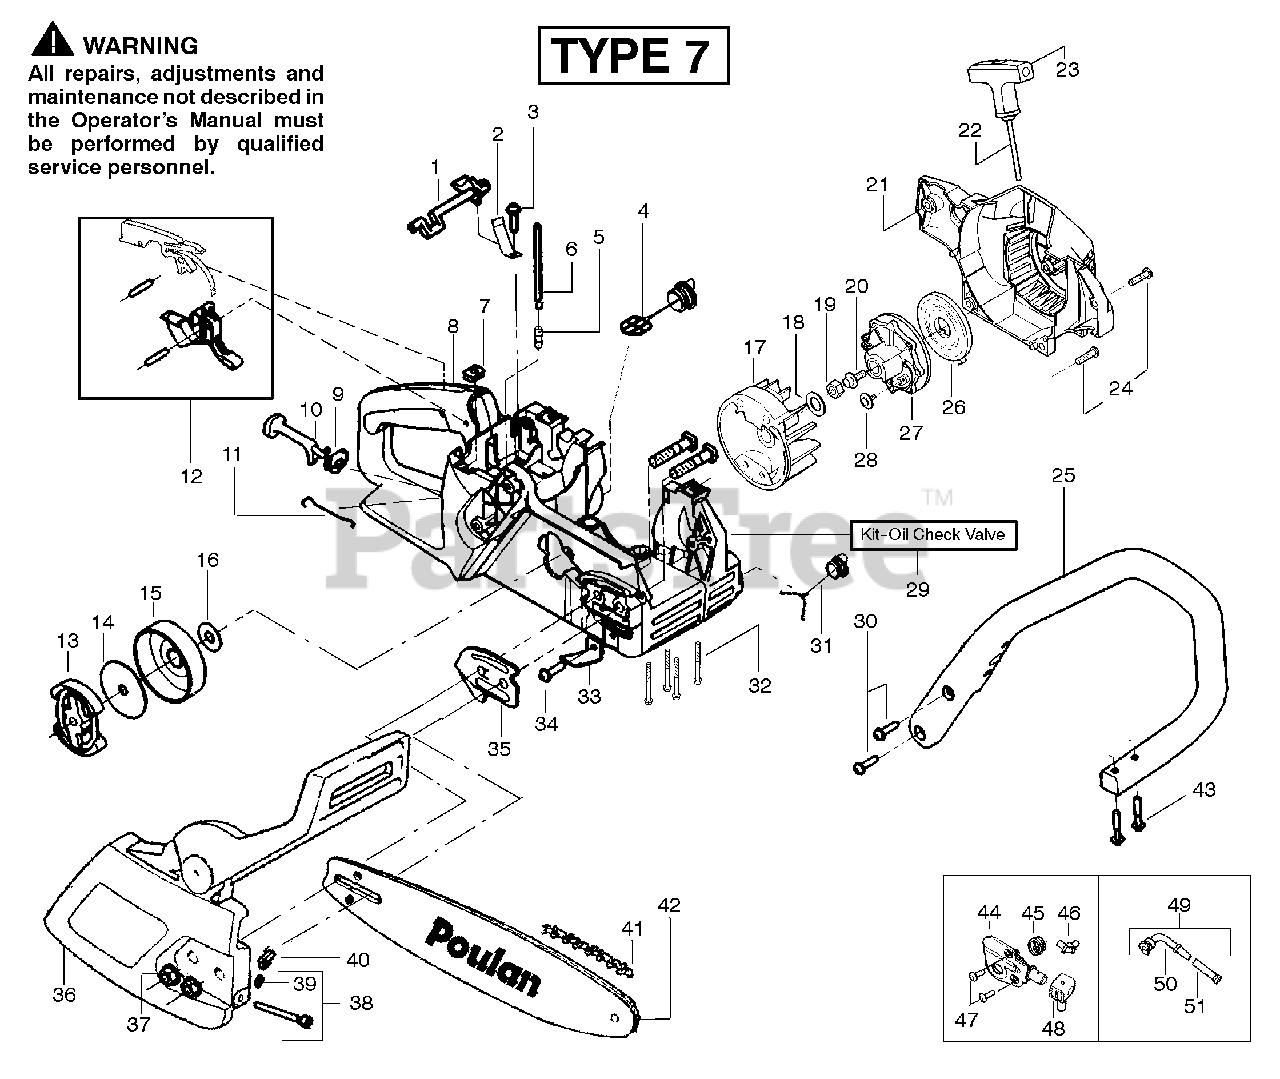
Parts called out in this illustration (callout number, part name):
1	Lever-Switch
2	Spring-Switch
4	Assy-Fuel Cap
6	Kit-Fuel Line (Large)
7	Nut-Speed
8	Assy-Chassis
9	Grommet-Choke Knob
10	Lever-Choke
11	Wire-Throttle
12	Kit-Trigger & Lockout
13	Assy. - Clutch
14	Washer-Clutch
15	Assy-Drum W/brg.
16	Washer - Thrust
17	Assy-Flywheel
18	Washer-Flywheel
19	Nut-Flywheel
21	Housing-Fan
22	Kit-Rope
23	Handle-Starter
25	Handle-Front
26	Spring-Starter
27	Pulley-Starter
29	Kit-Oil Check Valve
31	Assy-Oil Cap
33	Chain Catcher
35	Plate-Bar Mounting
36	Assy-Chain Brake
37	Nut-Bar Mounting
38	Kit-Bar Adjust
39	Retainer-Bar Adjust
40	Pin-Bar Adjust
41	Chain-14"
44	Kit-Oil Pump
45	Gear-Worm Spring
46	Elbow-Oil Pickup
48	Seal Block
49	Assy-Oil-Pickup
50	Pickup-Oiler
51	Filter-Oil
